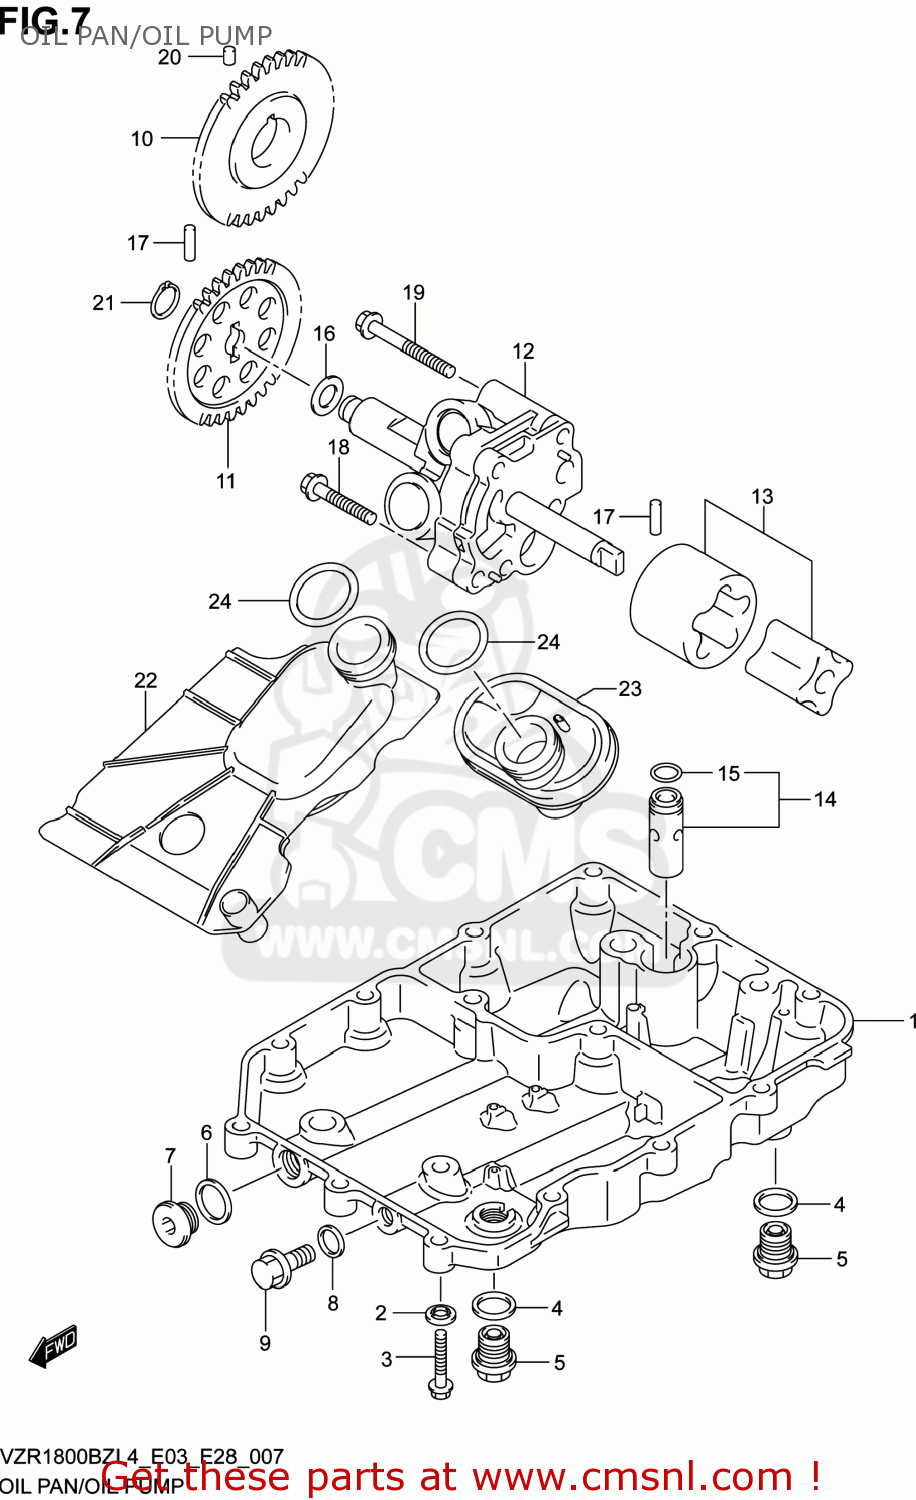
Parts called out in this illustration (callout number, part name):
1	PAN,OIL
2	GASKET(5.8X13X1.2) (NAS)
3	BOLT
4	GASKET(13.8X18.8X4.8) (NAS)
5	PLUG(14X20)
6	GASKET(16X22X2) (NAS)
7	PLUG,16X8
8	GASKET(10X14X3.6) (NAS)
9	PLUG(10X12)
10	GEAR,OIL PUMP DRIVE
11	GEAR,OIL PUMP DRIVEN
12	PUMP ASSY,ENGINE OIL
13	ROTOR SET,OIL PUMP
14	VALVE ASSY,OIL RELIEF(7K)
15	O RING(D:1.9,ID:13)
16	SHIM(10X18X0.5)
17	PIN(4X15.8)
18	BOLT
19	BOLT
20	PIN
21	CIRCLIP
22	STRAINER,ENGINE OIL FR
23	STRAINER,ENGINE OIL RR
24	O RING(D:3.7,ID:21.7)
